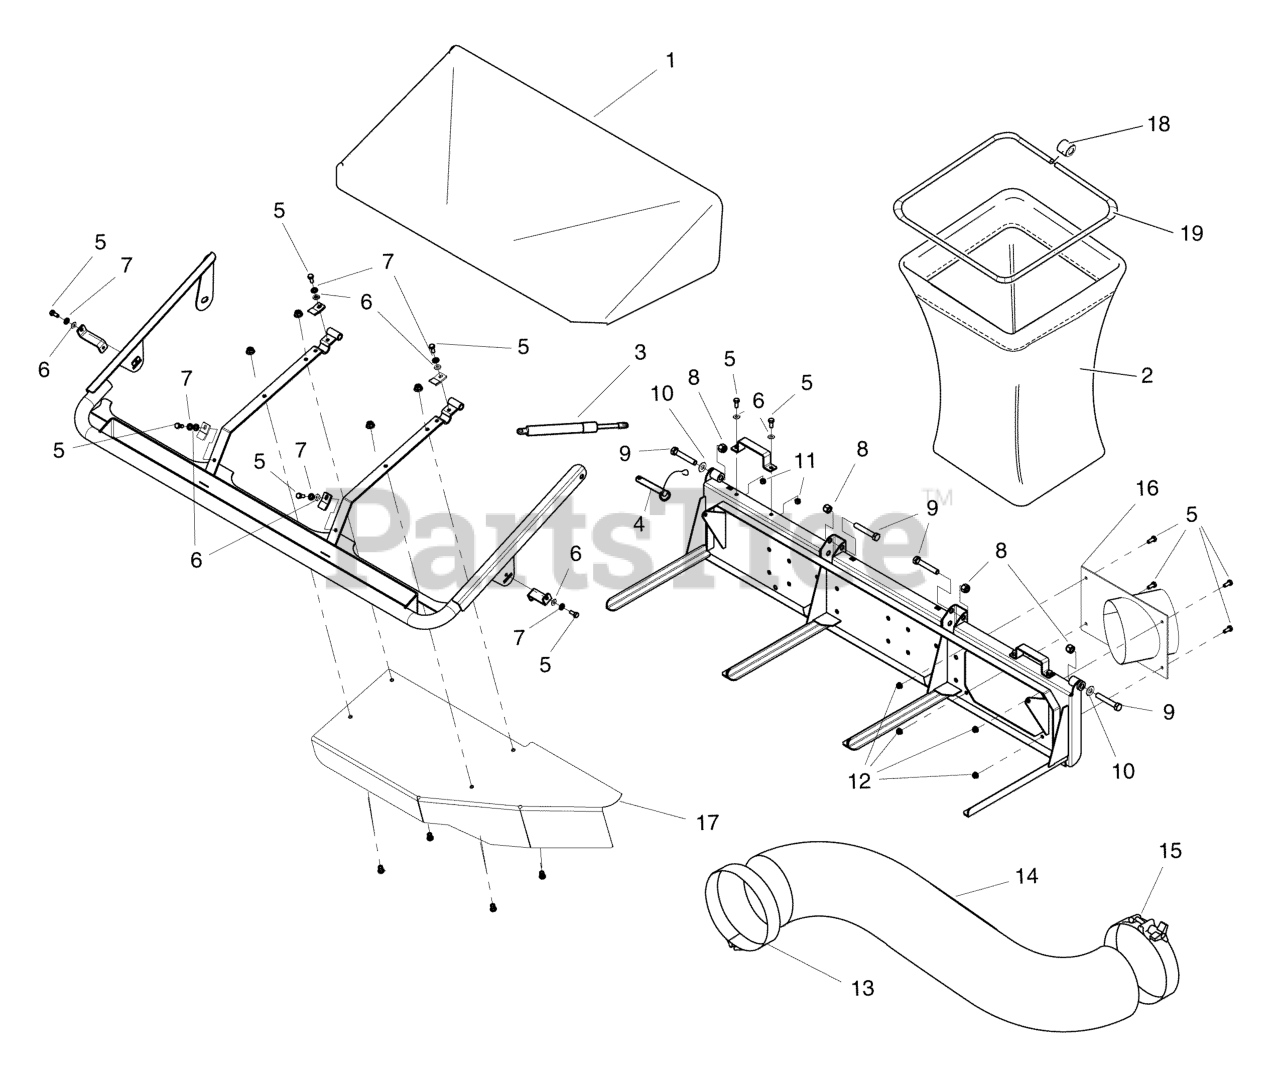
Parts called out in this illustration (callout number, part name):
1	3 BAG AIR DOME
2	CATCHER BAG W/ HANDLE
3	GAS CYLINDER
4	DETENT PIN W/ LANYARD
5	BOLT, 5/16-18 X 3/4 GD5
6	WASHER, 5/16" SAE
7	WASHER, 5/16 LOCK CZ
8	NUT, 1/2-13 HEX NYLON LOCK
9	BOLT, 1/2-20 X 3" GD5
10	WASHER, 1/2 SAE
11	NUT, 5/16-18 HEX NYLON LOCK
12	NUT, 5/16-18 HEX NYLOCK FLANGE
13	CLAMP, HOSE, UPPER
14	HOSE, FLEXIBLE, 7" DIA. X 58"
15	CLAMP, HOSE, LOWER
16	WELD, INLET BLOWER 3-BAG BLACK
18	BAG FRAME CONNECTOR, PLASTIC
19	BAG FRAME
